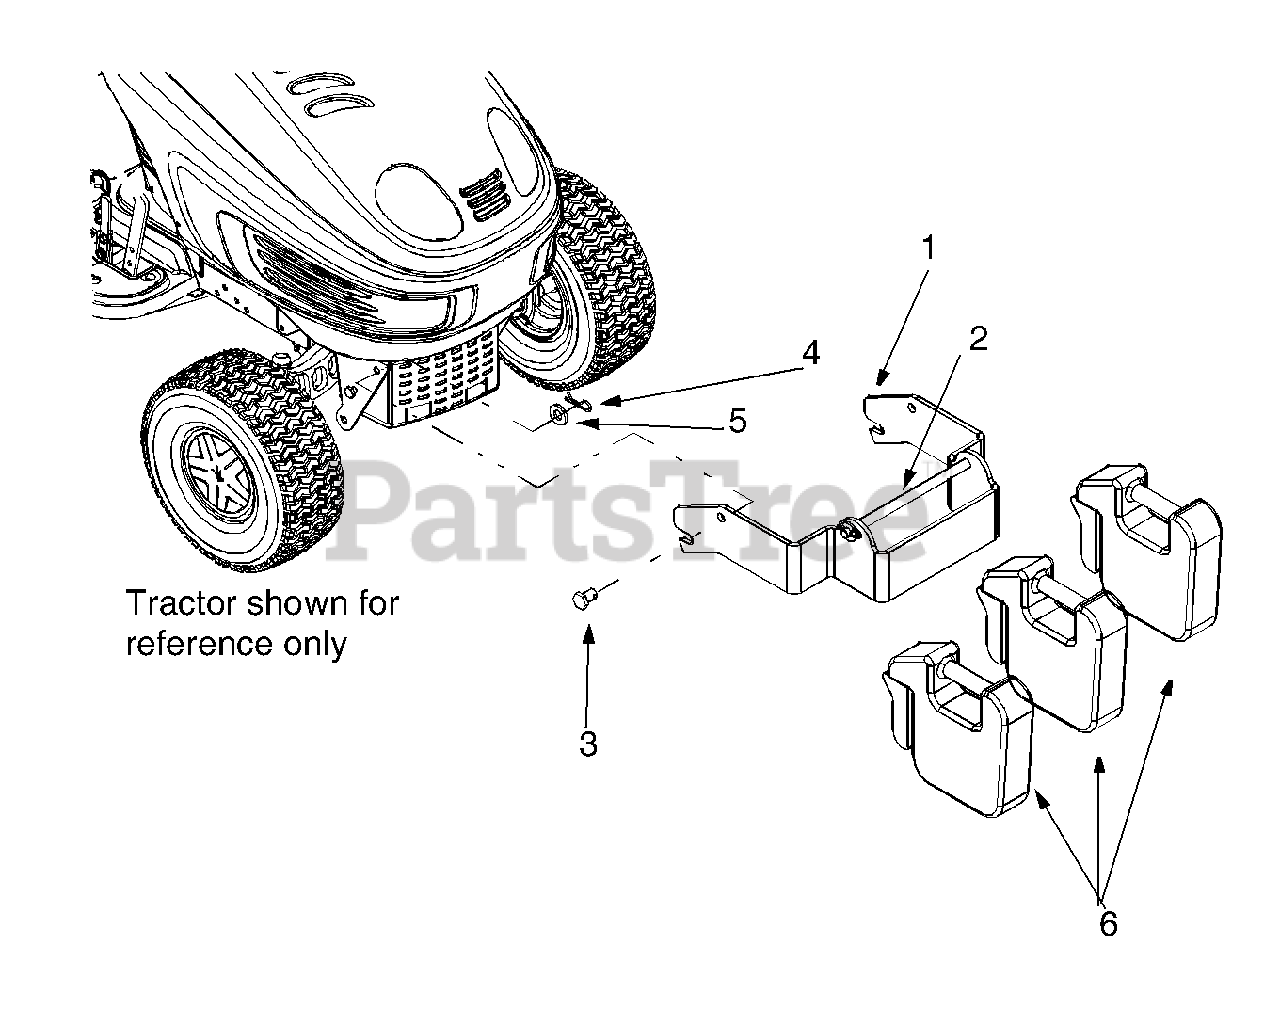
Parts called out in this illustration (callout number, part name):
3	Clevis Pin
4	Hairpin Clip
5	Flat Washer
6	Suitcase weight: 45 lb.
